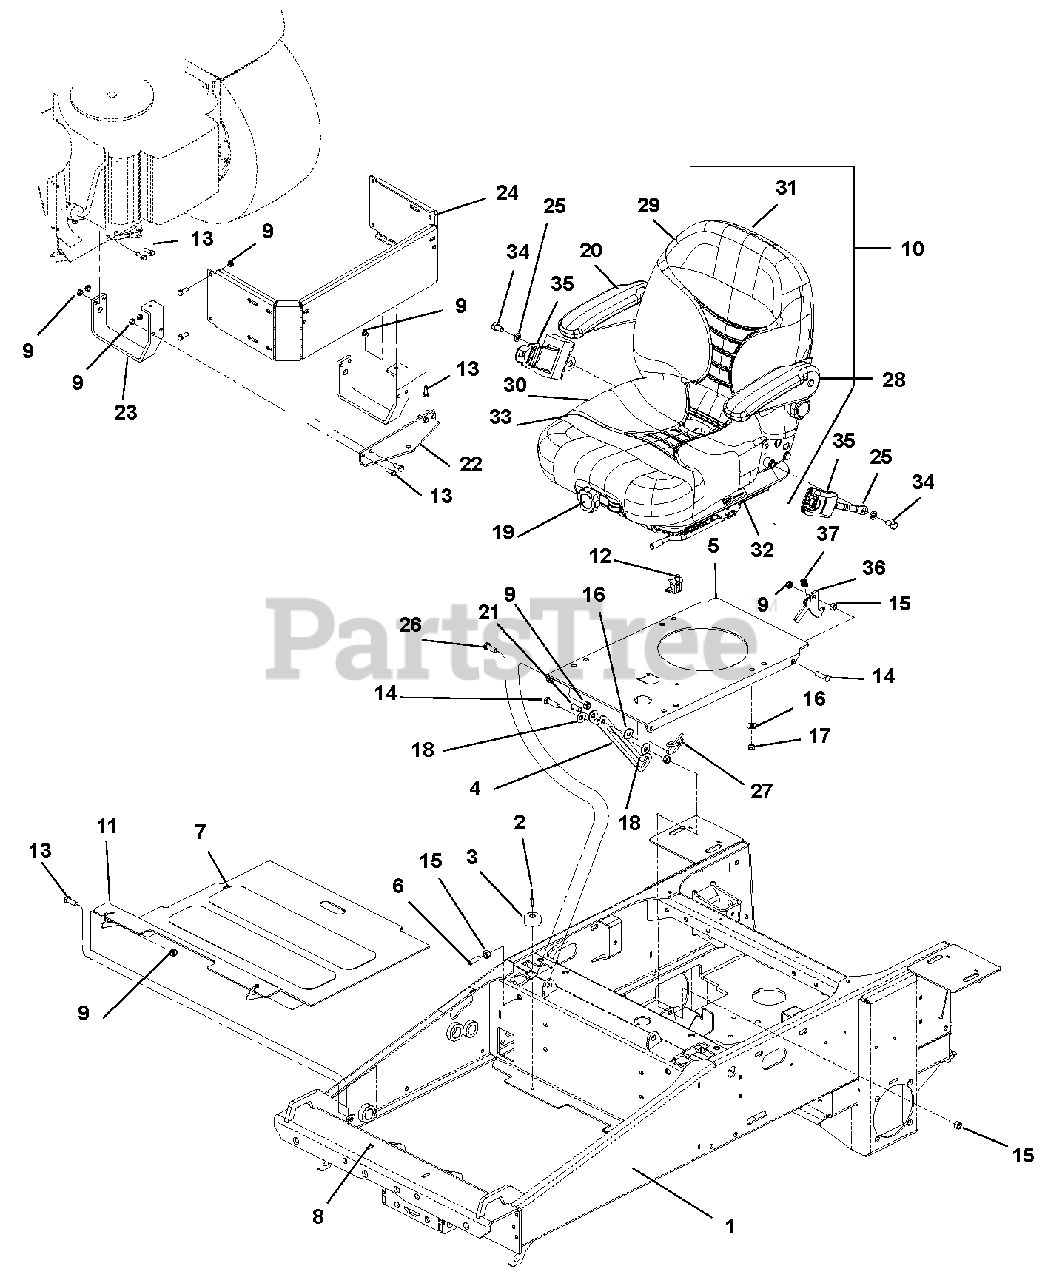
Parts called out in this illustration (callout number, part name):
1	Assembly, Frame with Decals (992220) (Serials 101 – 2499)
2	Rivet, 3/16 x .500 Pop
3	Bumper, Rubber .625 x 1.50 DIA
4	Bar, Seat Lock
5	Plate, Seat
6	Set Screw, 3/8-16 x 3/4 ALHD CUP
7	Traction Tape, 4 x 18
8	Traction Tape, 2.5 x 21.5
9	Nut, Locking, Flange .375-16
10	Seat, Full Suspension (Includes items 12, 19, 20 and 28 - 33)
11	Foot Plate
12	Seat Switch S/O
13	Bolt, 3/8-16 x 1.00 Hex 5
14	Bolt, 3/8-16 x 1.25 Hex 5
15	Nut, 3/8-16 STD Hex
16	Washer, Flat, Steel .38 x .875 x .083
17	Nut, Crown .312-18
18	Washer, Flat, Steel .438 x 1.00 x .083
19	Kit, Seat Knob
20	Kit, RH Armrest Assembly
21	Pin, Clevis .38 x .75
22	Plate, Hitch
23	Arm, Hitch Support
24	Plate, Rear Bumper (Serials 101 – 2499)
25	Washer, Locking .44 x .109 Regular
26	Bolt, Shoulder .5 x .106 x .38-16
27	Ring, Rue
28	Kit, LH Armrest Assembly
29	Kit, Back Cushion - Light Grey
30	Kit, Seat Cushion - Light Grey
31	Kit, Seat Back
32	Kit, Seat Slide
33	Kit, Seat Spring and Saddle
34	Bolt, Hex .44-20 x .75
35	Assembly, Seat Belt
36	Seat Latch
37	Spring, Com .600 x .056 x .875
